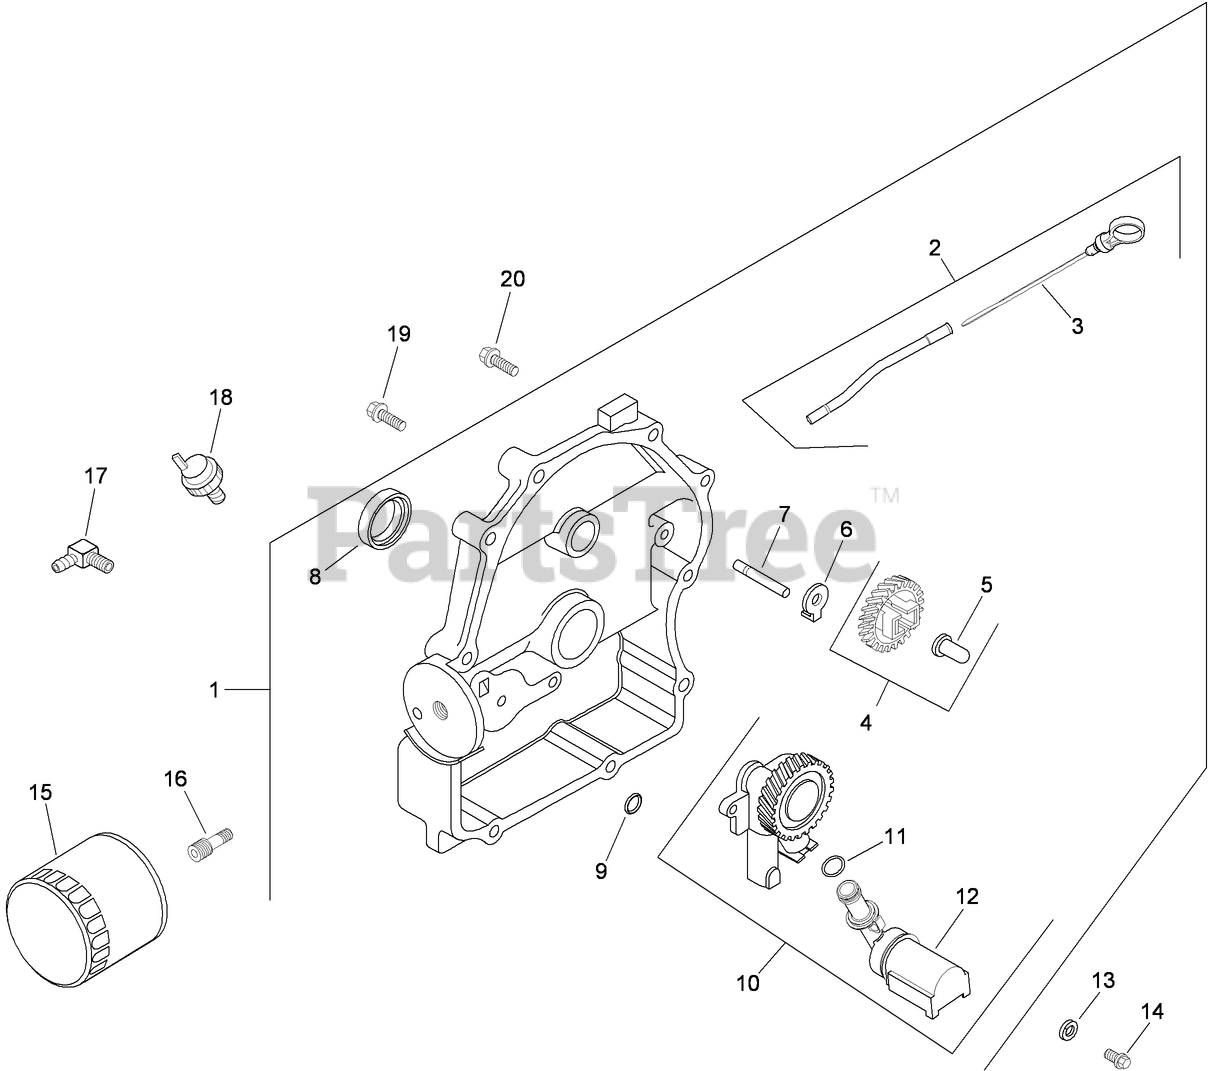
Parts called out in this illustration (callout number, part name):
1	Closure Plate Kit (Includes Ref 2-12)
2	DIPSTICK AND DIPSTICK TUBE ASM (Includes Ref 3)
3	Dipstick
4	GOVERNOR GEAR W/PIN KIT (Includes Ref 5)
5	PIN-REGULATING, GOVERNOR
6	Tab-Locking
7	SHAFT-GEAR, GOVERNOR
8	SEAL-OIL (P-T-O END)
9	O-Ring
10	Oil Pump ASM (Includes Ref 11, 12)
11	O-RING (oil pick?up)
12	TUBE-PICK UP, OIL
13	WASHER-FLAT (6 MM)
14	SCREW-FLANGE, THREAD FORMING (M6X1.0X25)
15	Filter-Oil
16	Nipple-Filter, Oil
17	Connector-Hose, 90 Deg
18	SWITCH-PRESSURE, OIL
19	Screw-HF (M8x1.25x45)
20	SCREW-FLANGE (M8X1.25X45)
